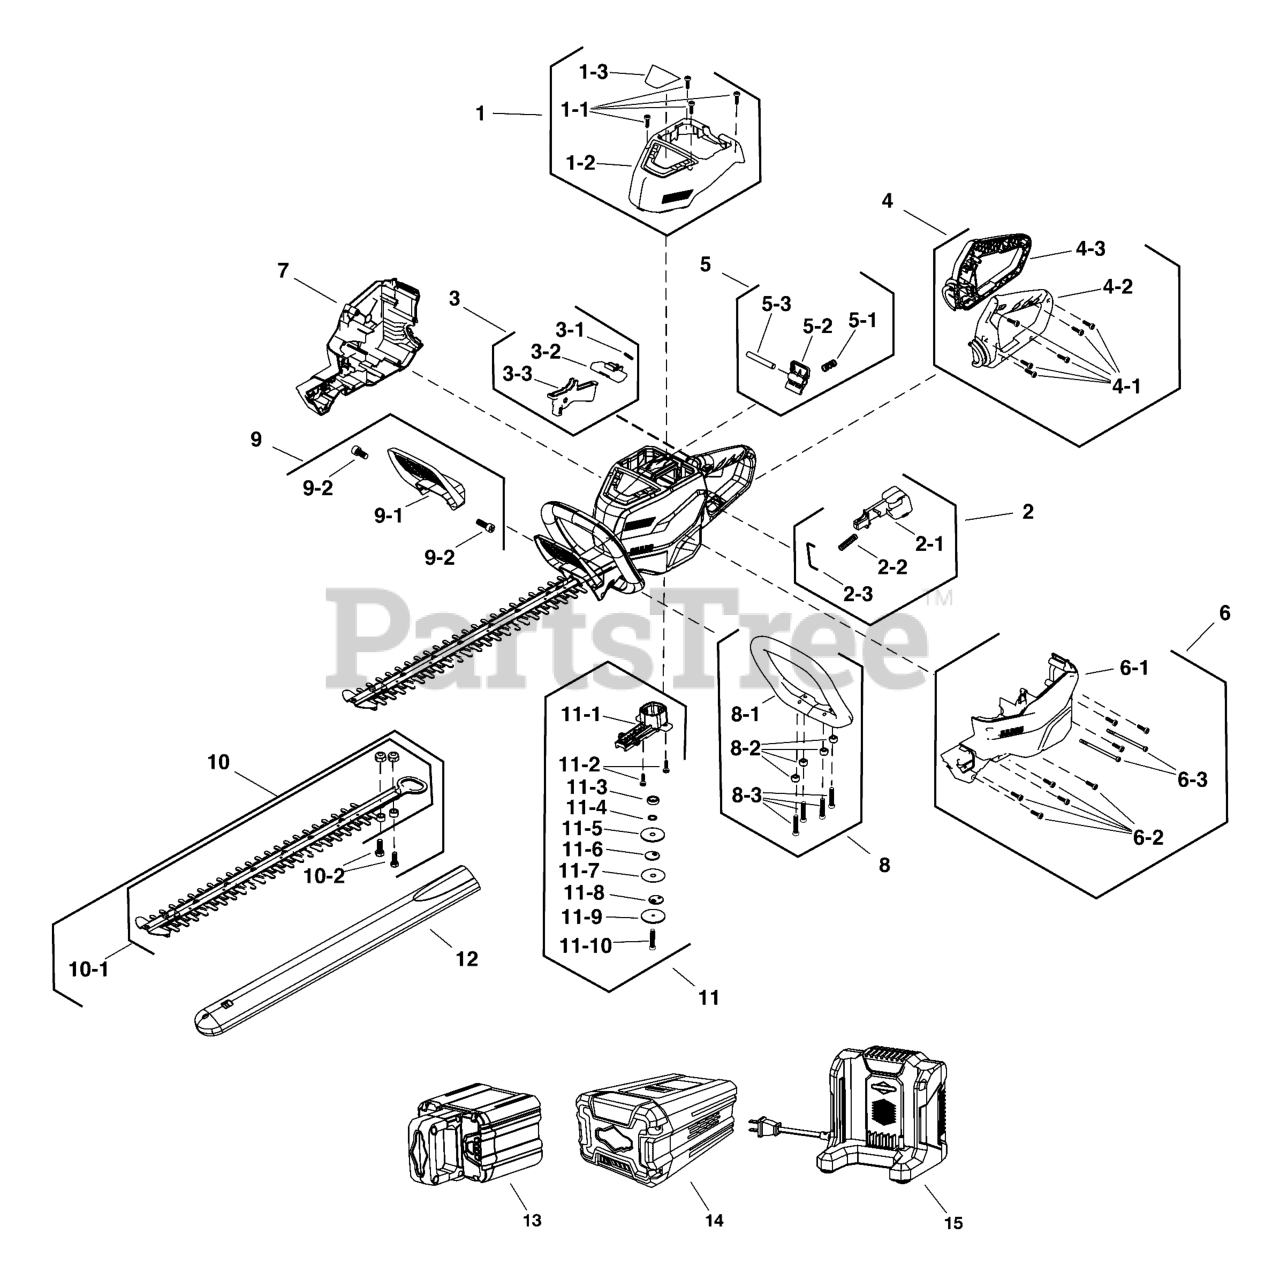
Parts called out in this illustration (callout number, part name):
1	KIT, Top Cover
1-2	COVER, Top
1-3	LABEL, Logo
2	KIT, Latch
2-1	LATCH
2-2	SPRING
2-3	WIRE FORM
3	KIT, Trigger
3-1	SPRING
3-2	BUTTON, Antlock
3-3	TRIGGER
4	KIT, Handle
4-2	HANDLE, Left
4-3	HANDLE, Right
5	KIT, Latch
5-1	SPRING
5-2	LEVER, Release
5-3	PIN
6	KIT, Side Cover, Left
6-1	COVER, Side, Left
7	KIT, Side Cover, Right
8	KIT, Handle
8-1	HANDLE
9	KIT, Guard
9-1	GUARD
10	KIT, Blade
10-1	BLADE ASSEMBLY
11	KIT, Gear Assembly
11-1	GEAR CASE
11-3	BEARING, Ball
11-4	GASKET
11-5	GASKET
11-6	CAM, Block
11-7	WASHER
11-8	CAM, Block
11-9	GASKET
12	COVER, Blade
13	* BATTERY, 2.0, 48V
14	* BATTERY, 5.0, 48V
15	* BATTERY CHARGER, 48V
